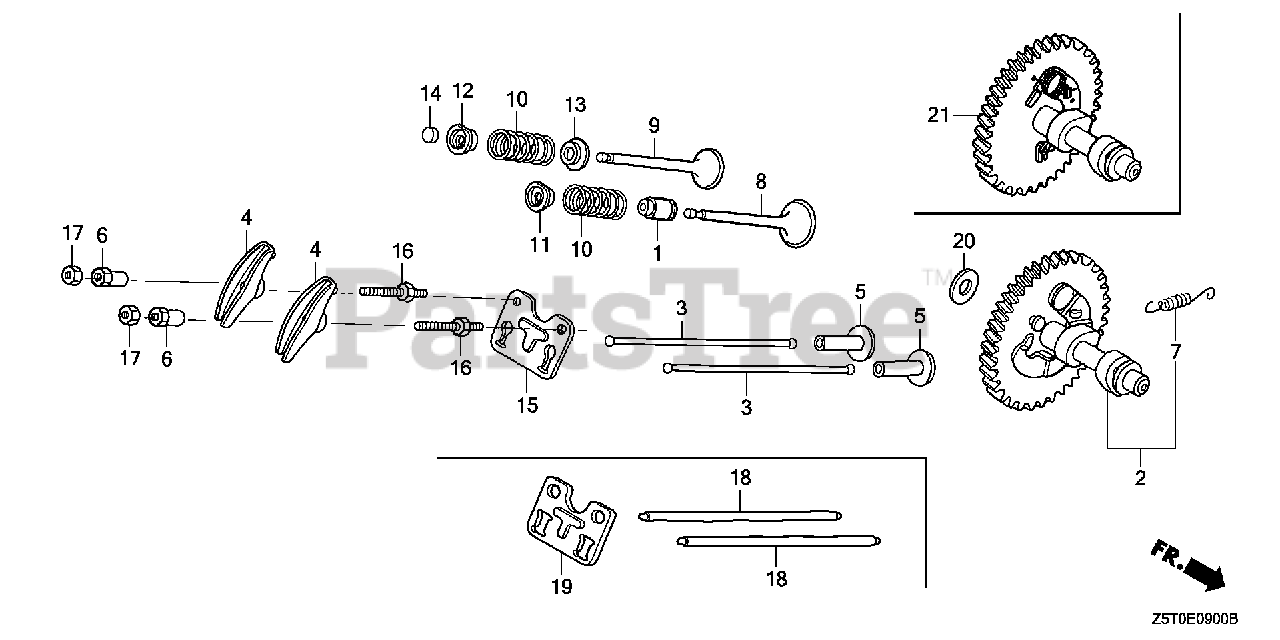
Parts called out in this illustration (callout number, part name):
1	SEAL, VALVE STEM
2	CAMSHAFT (STD)
4	ARM, VALVE ROCKER
5	LIFTER, VALVE
6	PIVOT, ROCKER ARM
7	SPRING, WEIGHT RETURN
8	VALVE, IN.
9	VALVE, EX.
10	SPRING, VALVE
11	RETAINER, IN. VALVE SPRING (EXHAUST SIDE)
12	RETAINER, IN. VALVE SPRING (EXHAUST SIDE)
13	SEAT, VALVE SPRING
15	GUIDE, PUSH ROD
16	BOLT, PIVOT (8MM)
17	NUT, PIVOT ADJ.
21	CAMSHAFT (STD)
